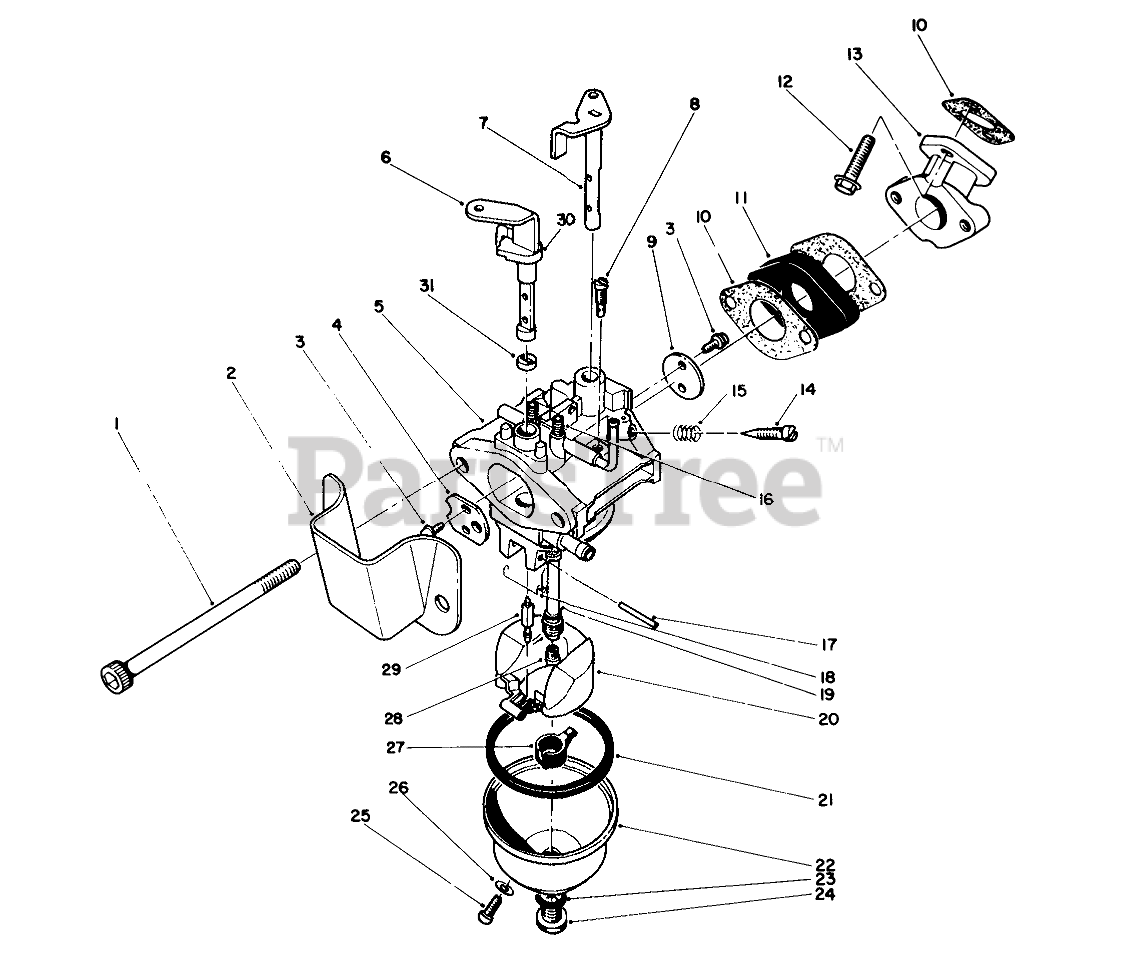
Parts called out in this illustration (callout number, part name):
2	SPIT CUP
3	Screw
4	VALVE
5	Body-Carburetor
6	Shaft-Choke (Incl. Ref. #30 & 31)
7	SHAFT
9	VALVE
10	Gasket-Carburetor
11	CARB INSULATOR
13	MANIFOLD
14	ADJUSTER
15	SPRING-PILOT SCREW
16	SPRING
17	PIN-HINGE
18	TORSION SPRING
19	MAIN NOZZLE
20	FLOAT
21	FLOAT BOWL GASKET
23	GASKET
24	SCREW
25	SCREW
26	GASKET
27	SPACER
28	MAIN JET
29	NEEDLE
30	UPPER CHOKE RING
31	LOWER CHOKE RING
